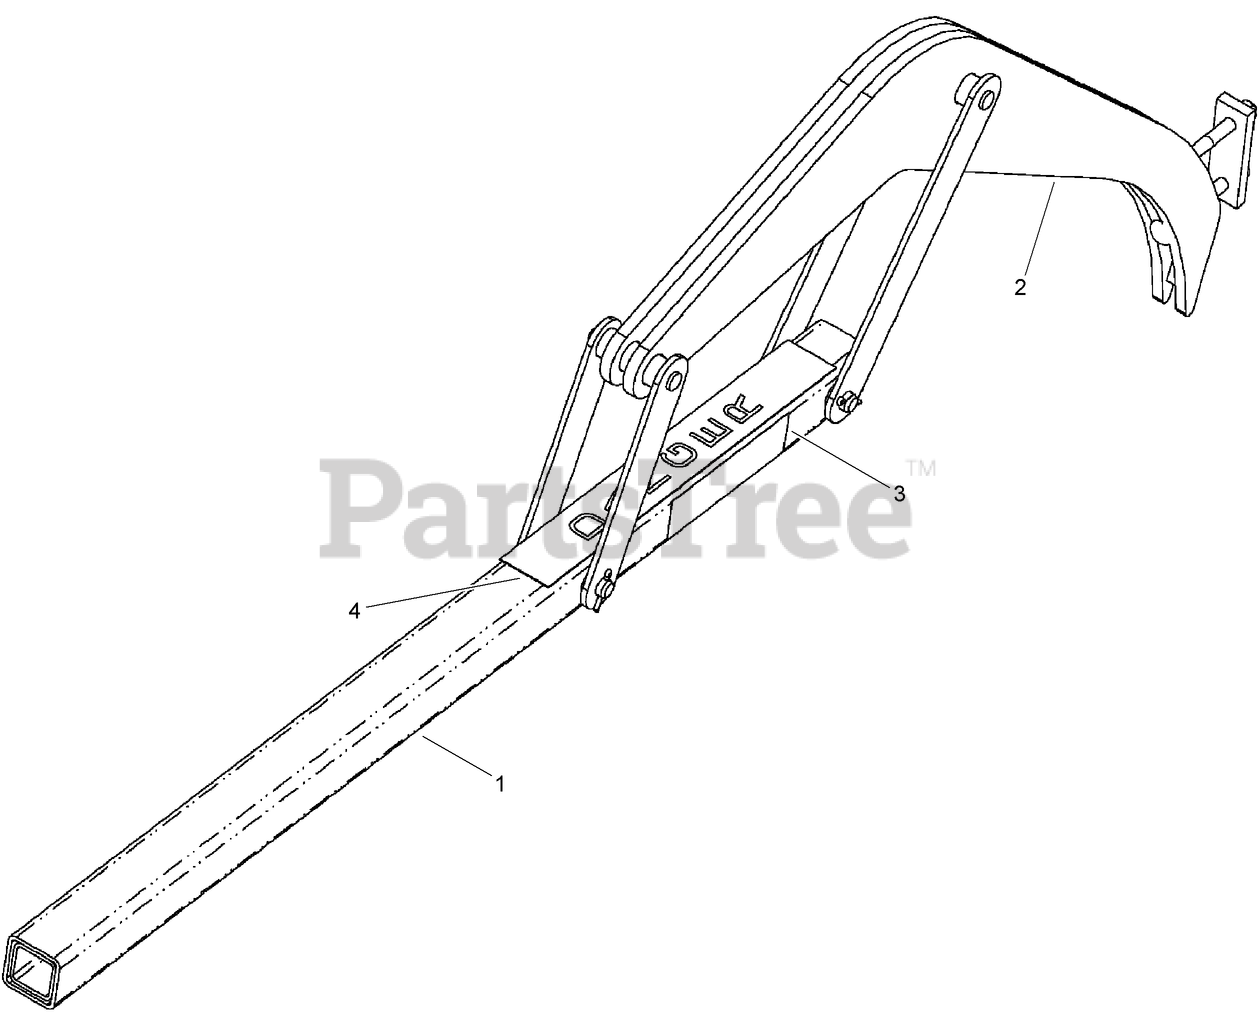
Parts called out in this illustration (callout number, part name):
1	BOOM-crumber, 5 foot, heavy duty planetary trencher
2	I / BASIC CRUMBER ASM
3	DECAL-Danger, Entanglement Hazard
4	DECAL-Danger
